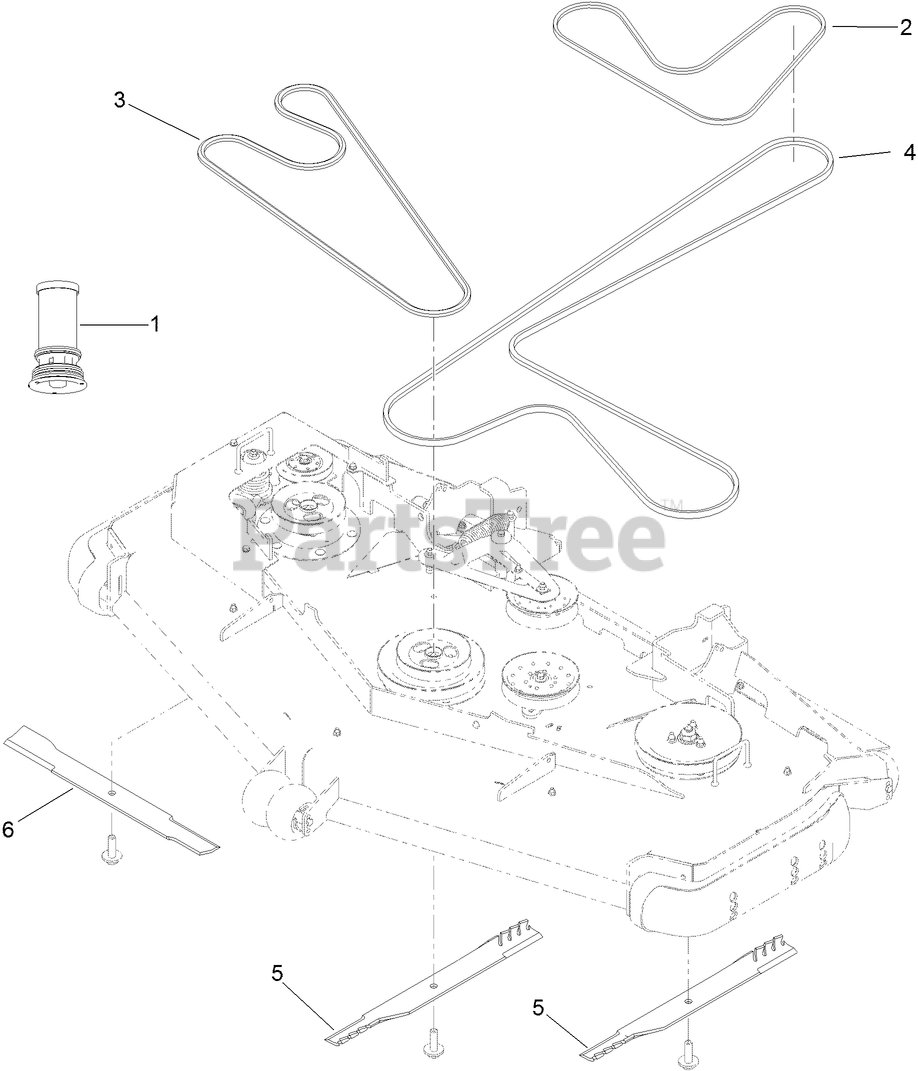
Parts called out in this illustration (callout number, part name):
1	FILTER-HYDRO
2	BELT
5	BLADE-ATOMIC, 24.5IN
6	BLADE-ROTARY, 24.5IN LOW FLOW (COUNTER ROTATION)
